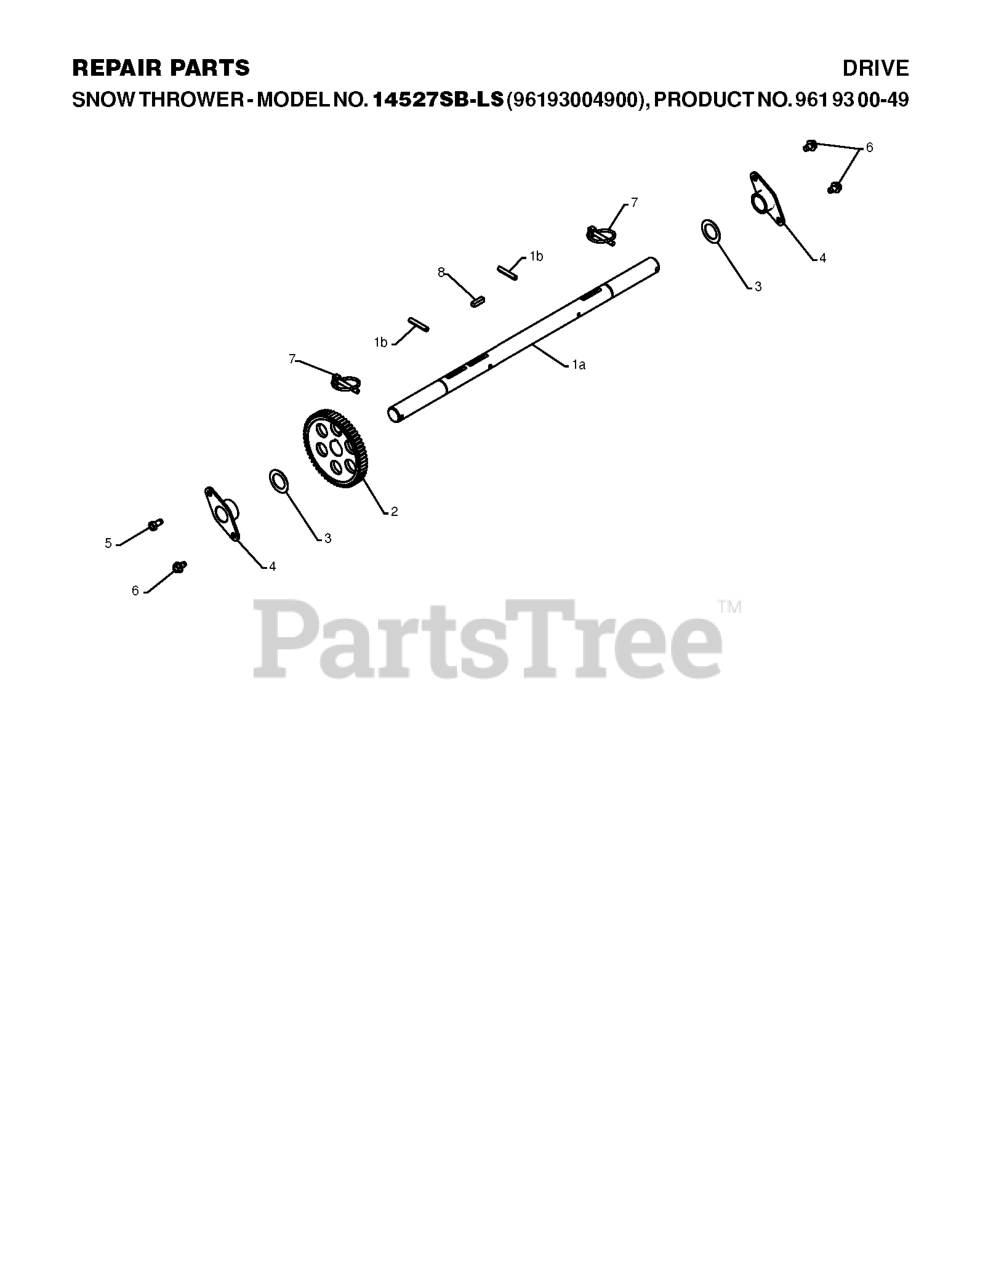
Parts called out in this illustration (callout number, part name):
1	AXLE.ASM.SHAFT.W/ROLLPIN.PS
2	GEAR, AXLE (58T)
3	WASHER TRUST 1"
4	BEARING, AXLE
6	Screw 5/16-18 x 1/2 Hex, Self Tapping 5/16-18 x 1/2
7	PIN KLIK, 1/4
8	KEY, SQUARE 1/4 X .875
